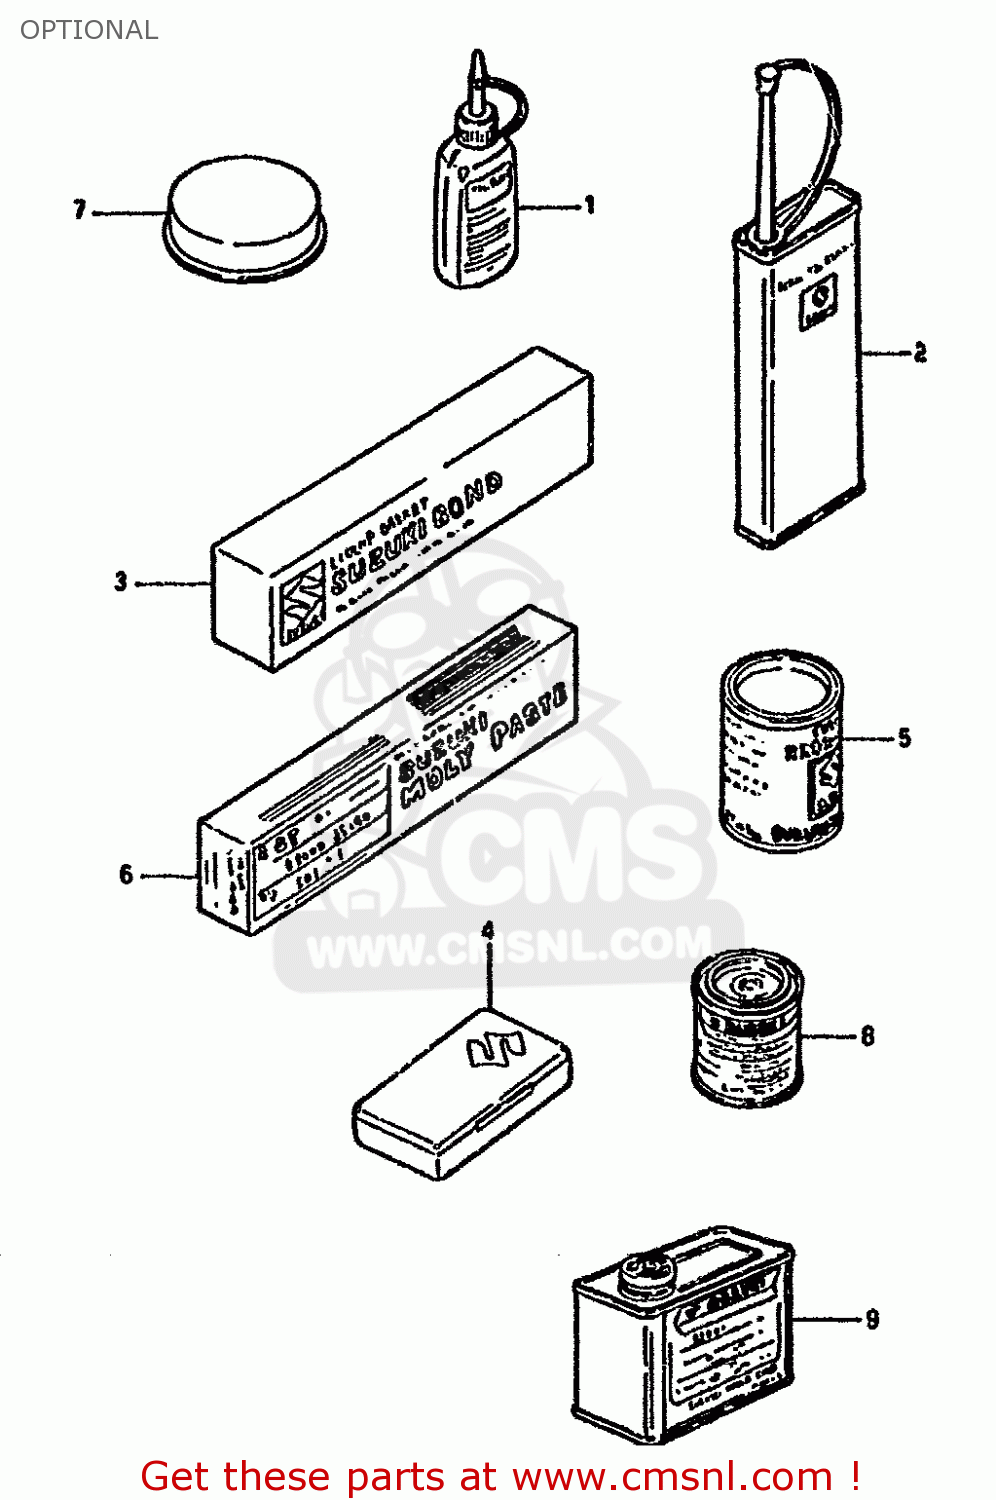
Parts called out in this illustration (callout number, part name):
1	THREAD LOCK NO.1342
2	THREAD LOCK NO.1401 CLEAR 200G
3	LIQUID GSKT NO.1207B 100G BLK
4	TUBE REPARING TOOL
5	GREASE(C)EP2 LITHIUM 150G
6	SUZUKI MOLY PASTE
7	GREASE,PBC FOR BRK PAD 20G
8	PAINT,BLACK
9	PAINT (BLACK)
